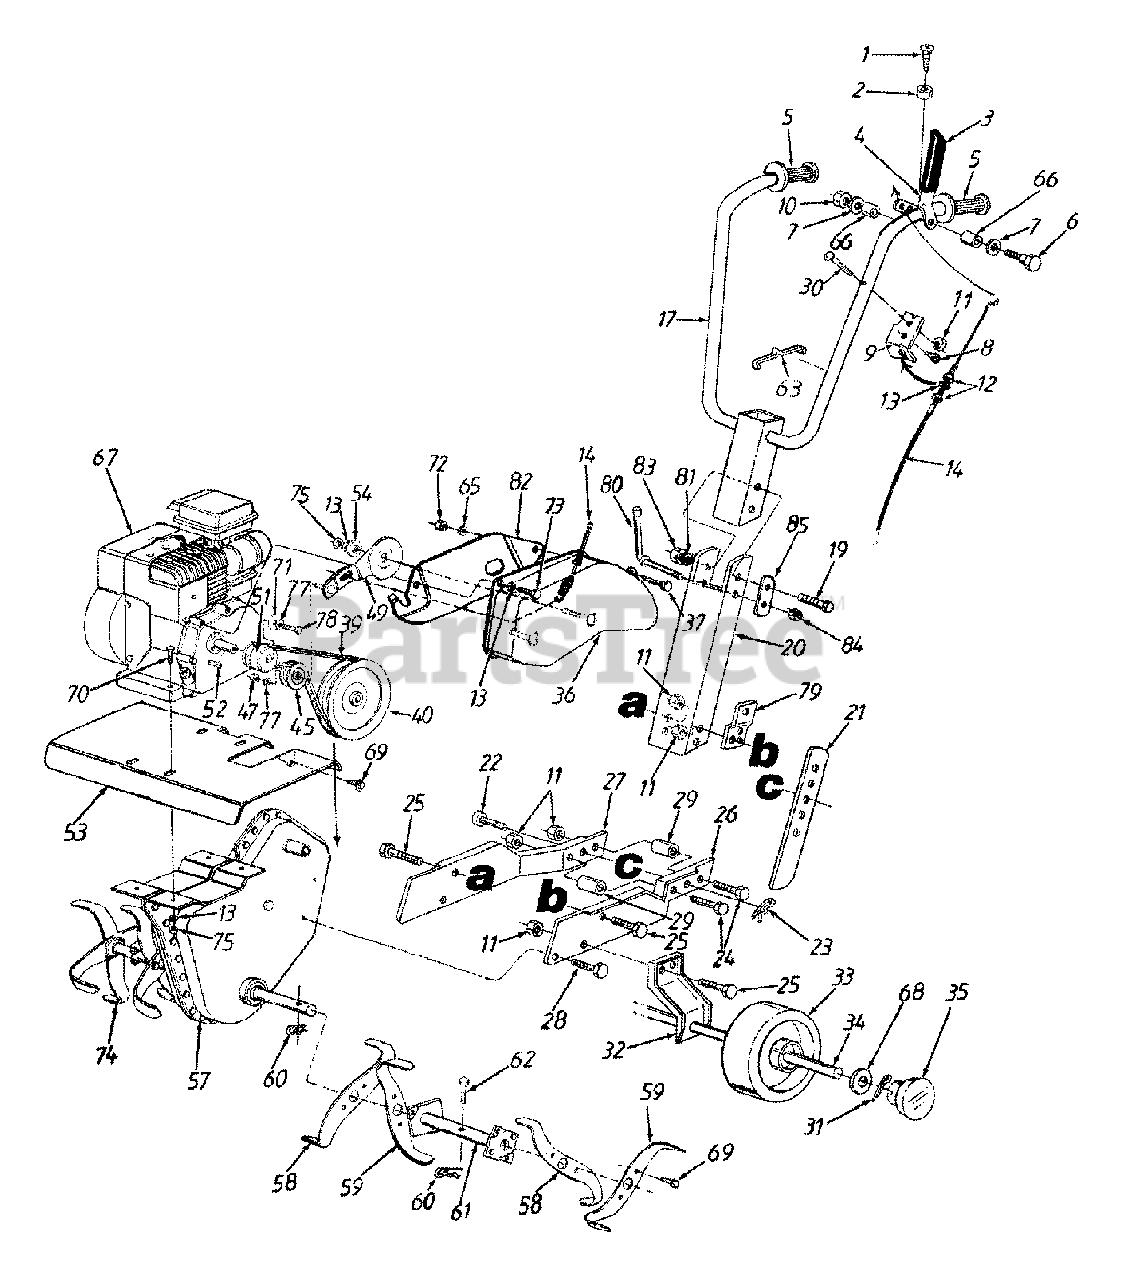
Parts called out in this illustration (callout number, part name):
1	Tap Scr. #10-16 x 1/2" Lg.
2	Rubber Bumper
3	Vinyl Grip
4	Clutch Lever Ass'y.
5	Handle Grip
6	Hex Bolt 1/4-20 x 2" Lg.
7	Fl-Wash. 1/4" I.D.
8	Hex Tap Scr. 1/4-20 x 1/2" Lg.
9	Cable Bracket
10	Lock Nut 1/4-20 Thd.
11	Lock Nut 5/16-18 Thd.
12	Hex Jam Nut 5/16-24 Thd.
13	L-Wash. 5/16" I.D.
14	Clutch Control Cable
17	Handle Ass'y.
19	Carr. Bolt 5/16-18 x 2-1/2" Lg.
20	Handle Channel - Frame
21	Depth Stake
22	Clevis Pin
23	Hairpin Cotter
24	Hex Bolt 5/16-18 x 1" Lg.
25	Hex Bolt 5/16-18 x 5/8" Lg.
26	L.H. Frame Half
27	R.H. Frame Half
28	Hex Tap. Scr. 5/16-18 x 1/2" Lg.
29	Spacer
30	Hex Bolt 5/16-18 x 1-1/4" Lg.
31	Cotter Pin
32	Wheel Bracket
33	Wheel - 6"
34	Axle - Wheel
35	Hub Cap
36	Belt Cover
37	Hex Bolt 1/4-20 x 5/8" Lg.
39	V-Belt
40	Pulley - Chain Case
45	Flat Idler Pulley
47	Hex Jam L-Nut 3/8-24 Thd.
49	Idler Arm Ass'y.
51	Engine Pulley
52	Square Key 3/16" x .75" Lg.
53	Tine Shield
54	Washer - Bushing
57	Chain Case Ass'y. Comp.
58	R.H. Tine Blade
59	L.H. Tine Blade
60	Hairpin Cotter
61	Adapter Ass'y. - Tine
62	Clevis Pin
63	Cable Tie - Plastic
66	Spacer
67	Engine
68	Fl-Wash. 3/8" I.D.
69	Tap Scr. 1/4-20 x 1/2" Lg.
70	Hex Bolt 5/16-18 x 1-1/2" Lg.
71	Fl-Wash. 3/8" I.D. x 1" O.D.
72	Hex Nut 1/4-20 Thd.
73	Hex Bolt 5/16-24 x .5" Lg.
74	Tine Blade Ass'y. Comp.
75	Hex Nut 5/16-18 Thd.
77	L-Wash. 3/8" I.D.
78	Hex Bolt 3/8-24 x 1" Lg.
79	Belt Cover Bracket
80	Handle Lever
81	Fl-Wash. .385" I.D. x .87" O.D.
82	Belt Cover-Rear
83	Hex L-Nut 3/8-16 Thd.
84	Hex Flange L-Nut 3/8-24 Thd.
85	Retainer Bracket
